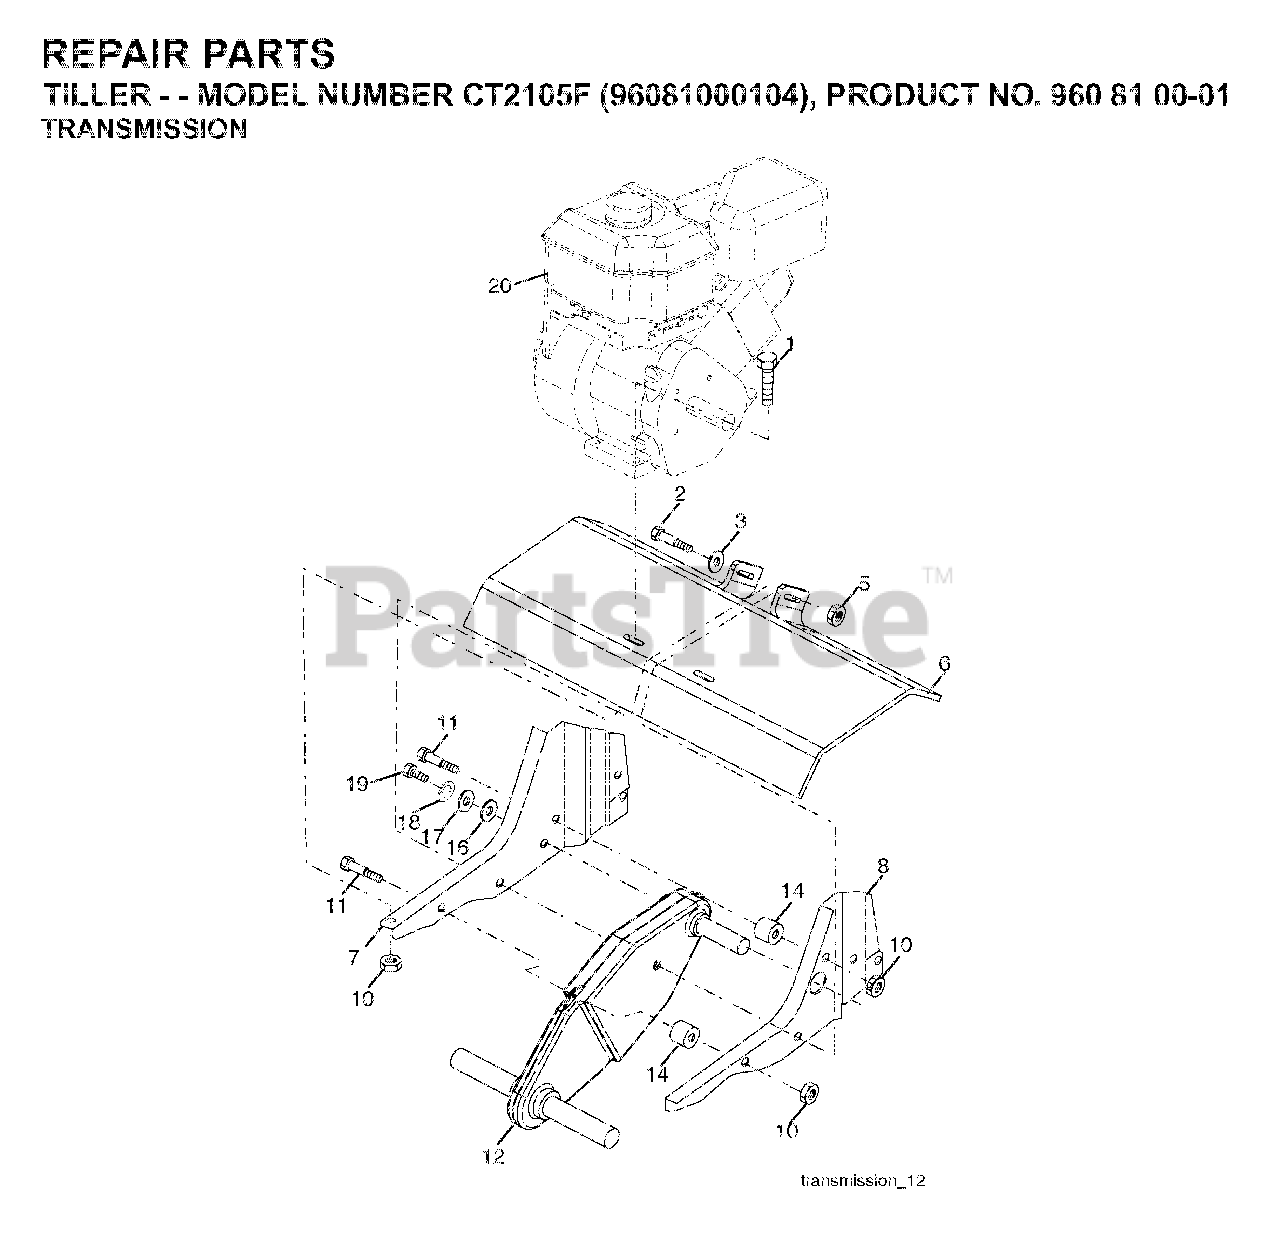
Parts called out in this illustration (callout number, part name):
1	BOLT
3	WASHER
5	NUT LOCK FLG 3/8-16 UNC
7	RP BRACKET, ENGINE, R.H.
8	BRKT.ENGINE.LH.BLACK
10	LOCKNUT-FLANGE 5/16-18
11	BOLT, HEX HEAD 5/16-18 X 2.5
12	TRANSMISSION.ASM.W/1".D-SHAFT
18	LOCKWASHER
